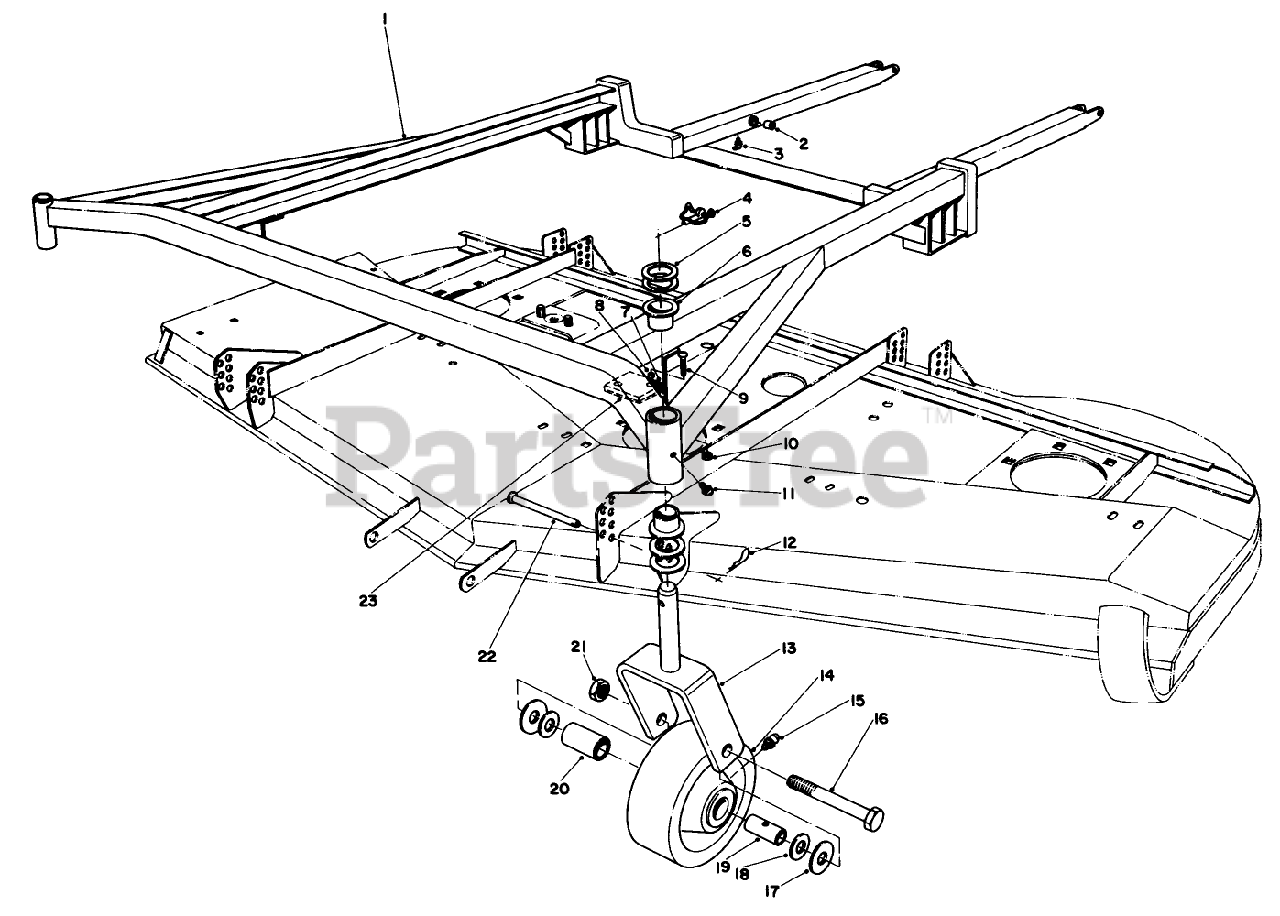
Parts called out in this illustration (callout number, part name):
2	7/8 ID X 1.128 X 7/8 LG BSHG
3	FITTING-GREASE, 90 DEG
4	PIN-LYNCH
5	WASHER-THRUST
7	CUSHION-RUBBER
8	SPACER
10	NUT-LOCK, NI
11	FITTING-GREASE
12	PIN-HAIR
14	CASTOR WHEEL
15	GREASE FITTING
16	SCREW-HH
17	THRUST WASHER
18	BEARING RETAINER
19	SPANNER BUSHING
20	ROLLER BEARING
21	NUT-LOCK
22	PIN-CLEVIS
23	SHIM-CUSHION
